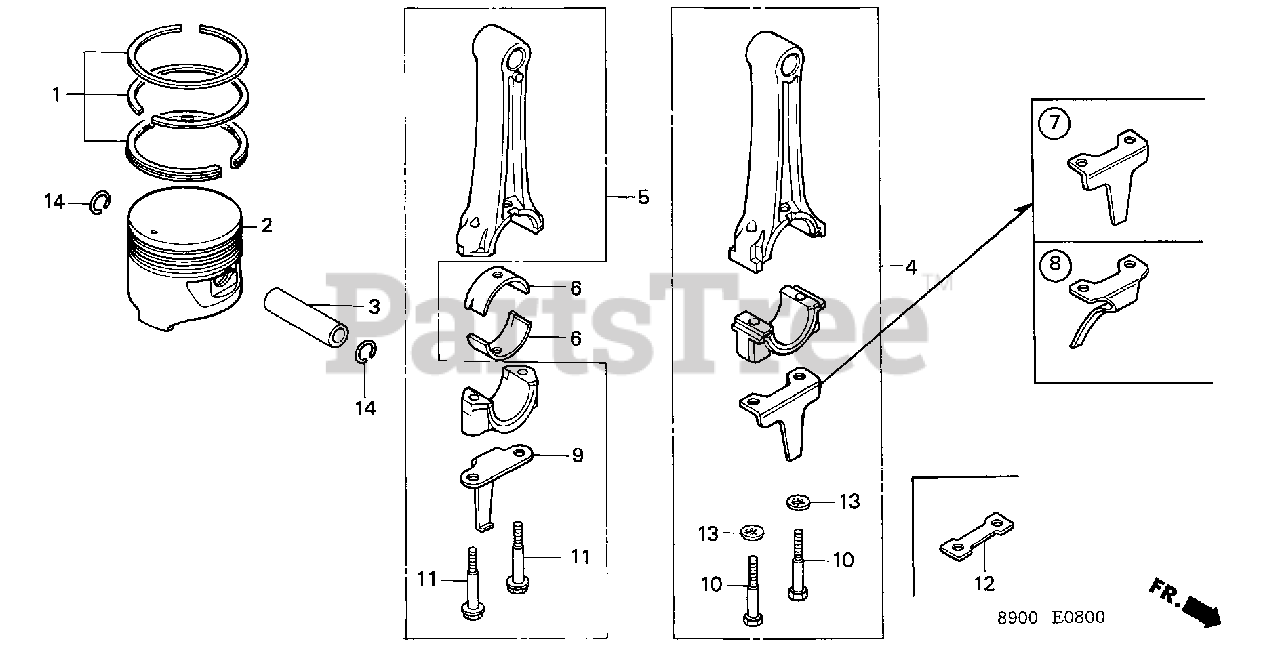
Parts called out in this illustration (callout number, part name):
1	RING SET, PISTON (STD)
1	RING SET, PISTON (STD) (NOT AVAILABLE)
1	RING SET, PISTON (0.25)
1	RING SET, PISTON (0.50)
1	RING SET, PISTON (0.75) (NOT AVAILABLE)
2	PISTON (STD)
2	PISTON (0.25)
2	PISTON (0.50)
2	PISTON (0.75)
3	PIN, PISTON
5	ROD ASSY., CONNECTING
6	BEARING A, CONNECTING ROD (BLACK)
6	BEARING B, CONNECTING ROD (BROWN)
6	BEARING C, CONNECTING ROD (GREEN)
6	BEARING D, CONNECTING ROD (YELLOW) (NOT AVAILABLE)
6	BEARING E, CONNECTING ROD (PINK)
6	BEARING A, CONNECTING ROD (0.25 LOWER SIZE) (BLUE) (NOT AVAILABLE)
6	BEARING B, CONNECTING ROD (0.25 LOWER SIZE) (WHITE)
6	BEARING C, CONNECTING ROD (0.25 LOWER SIZE) (RED) (NOT AVAILABLE)
9	DIPPER, CONNECTING ROD
11	BOLT, CONNECTING ROD (8MM) (NOT AVAILABLE)
11	BOLT, CONNECTING ROD (8MM)
14	CLIP, PISTON PIN (19MM)
